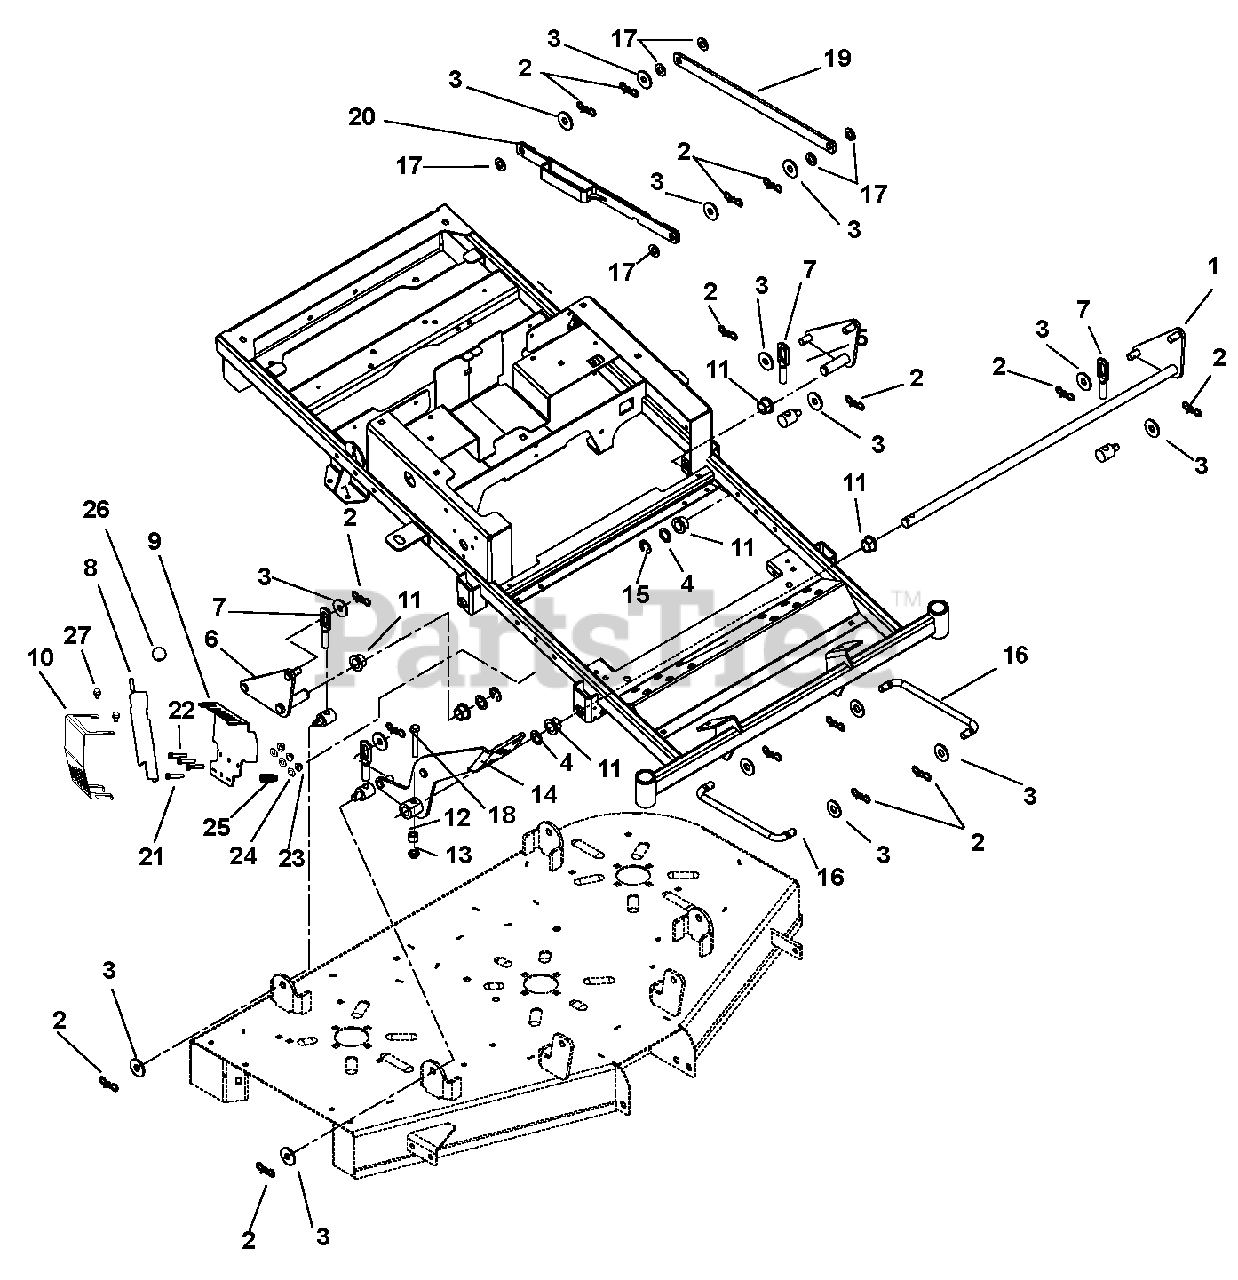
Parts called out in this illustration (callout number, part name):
1	Weldment, Deck Pivot
2	Pin, Bow Tie Locking Cotter .091 x 1.875
3	Washer, Flat Steel.511 x 1.441 x .125
4	Washer, Flat Steel .754 x 1.125 x .062
5	Weldment, Deck Pivot ZTXL Rear Left Hand
6	Weldment, Deck Pivot ZTXL Rear Right Hand
7	Assembly, Deck Link
8	Lever, Weldment
9	Bracket, HOC XL
10	Guard, Plate Styled HOC
11	Bushing, Flange .750 x 1.000 x .625 x 1.250
12	Bushing, Sleeve .391 x .688 x .52
13	Nut, Flange Nyloc 3/8-16
14	Weldment, ZTXL Foot Pedal
15	Ring, Retaining-External .750 x .050
16	Link, Drag
17	Washer, Flat Nylon .52 x 1.00 x .08
18	Bolt, Hex .38-16 x 2.50 Grade 5
19	Link, Lift
20	HOC, Link Retaining XL
21	Bolt, Hex .38-16 x 2.25
22	Bolt, Hex .38-16 x 1.75 Grade 5
23	Nut .38-16 Nyloc Flange
24	Washer, Flat Steel .38 x .875 x .083
27	Screw, Tapping Hex Washer Head Thread Rolling .25-20 x .50 YWZ
